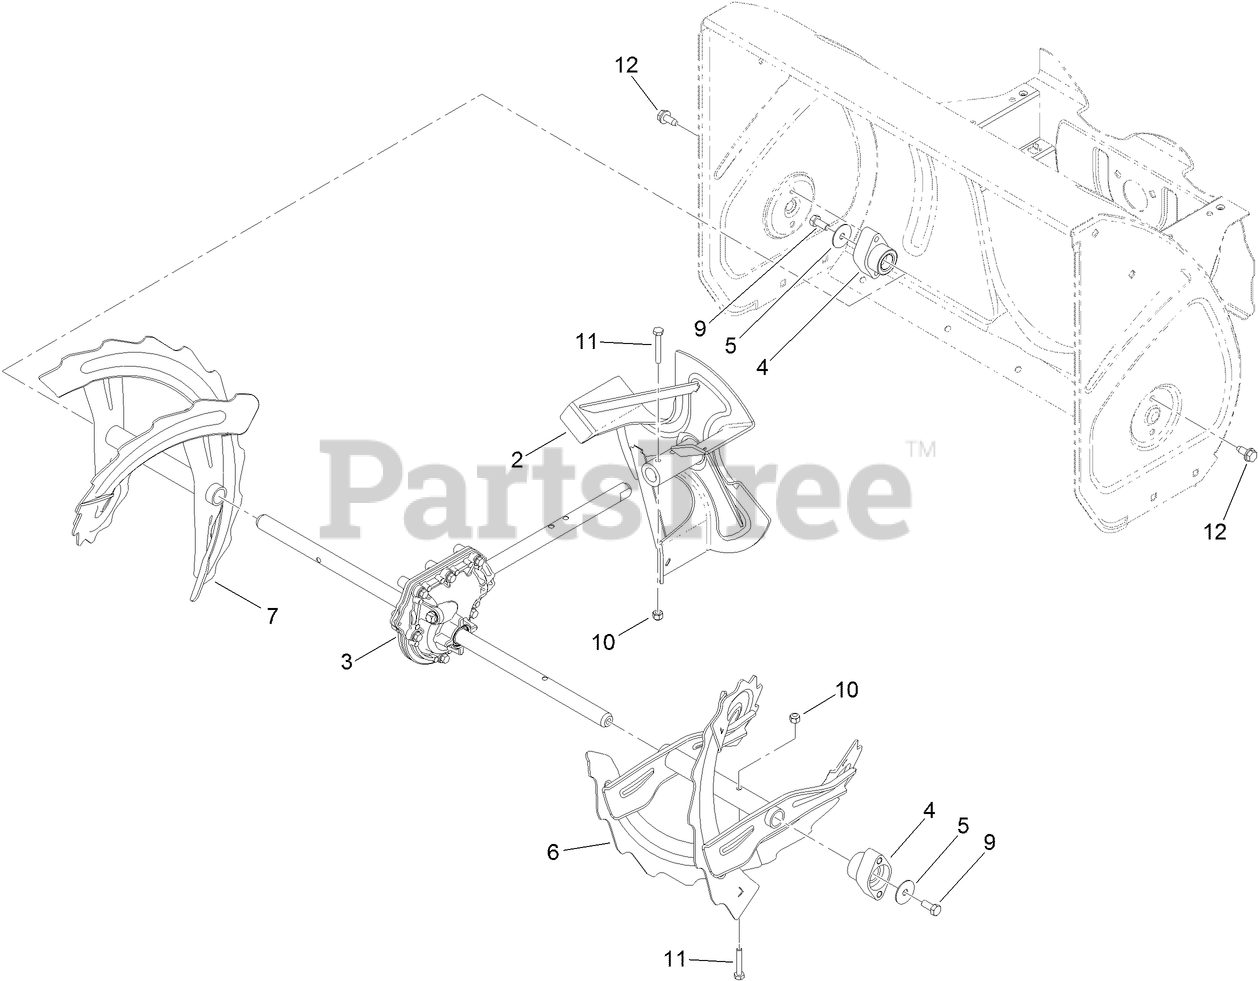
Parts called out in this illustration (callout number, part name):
2	IMPELLER ASM
3	GEARCASE ASM
4	BEARING-AUGER
5	WASHER-THRUST
6	LH AUGER ASM
7	RH AUGER ASM
9	SCREW-HH
10	NUT-LOCK, NI
11	SCREW-HH
12	SCREW-HWHTF
